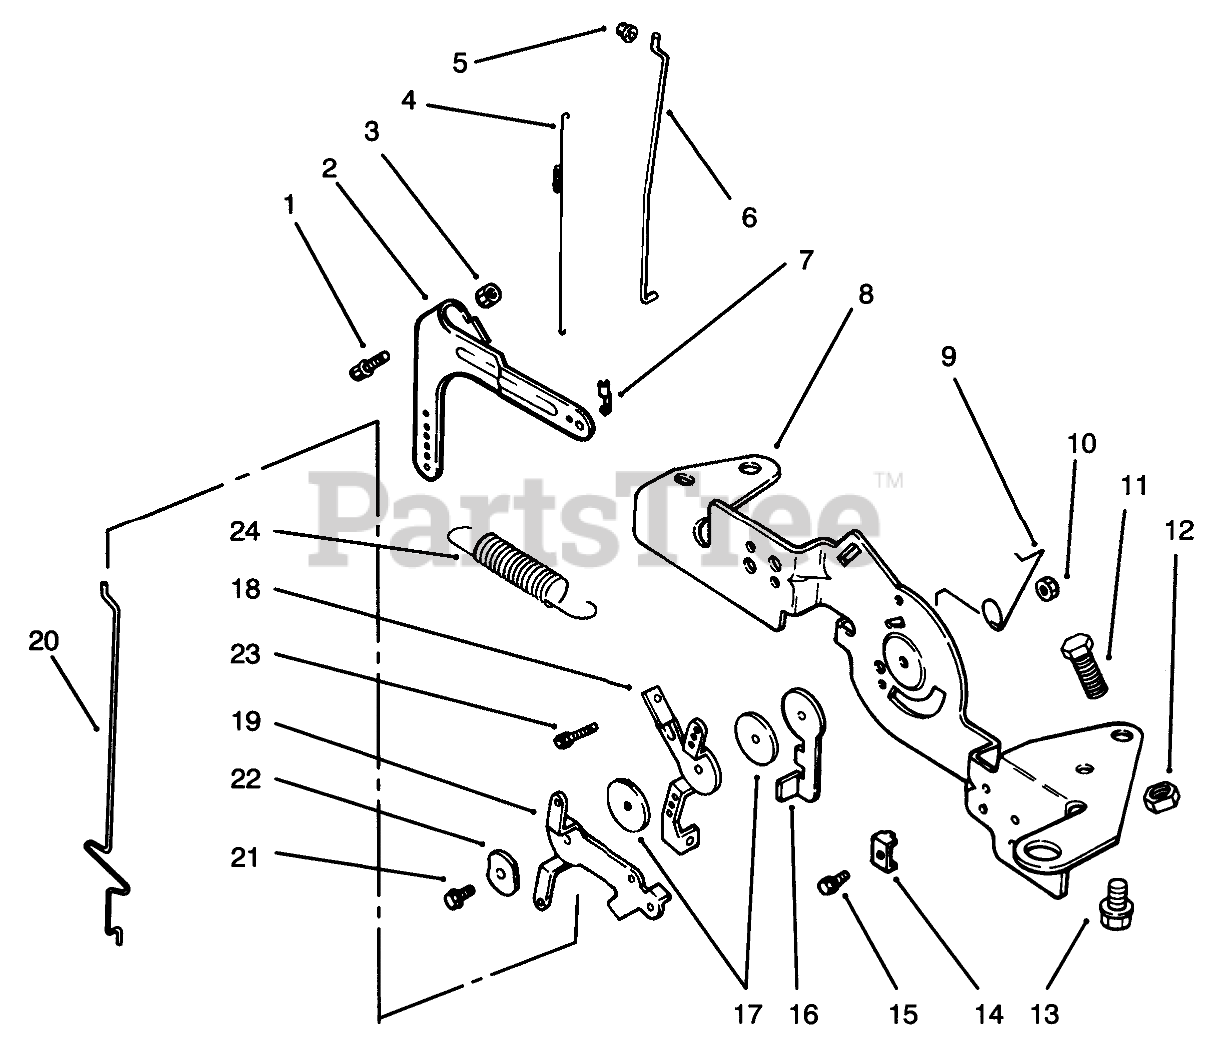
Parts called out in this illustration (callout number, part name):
1	Screw M6x1.0x25 (Only On: 72103)
2	Lever-Governor (Only On: 72103)
3	Nut M6x1.0 (Only On: 72103)
4	Spring-Linkage (Only On: 72103)
5	Bushing-Linkage (Only On: 72103)
6	Linkage-Throttle (Only On: 72103)
7	Bushing-Linkage (Only On: 72103)
8	Bracket-Control (Only On: 72103)
9	Spring-Choke Return (Only On: 72103)
10	Nut M5x0.8 (Only On: 72103)
11	Screw M5x0.8x16 (Only On: 72103)
12	Nut-Hex M4x0.7 (Only On: 72103)
13	Screw M6x1.0x16 (Only On: 72103)
14	Clamp-Cable (Only On: 72103)
15	Screw M5x0.8x16 (Only On: 72103)
16	Lever-Throttle Actuator (Only On: 72103)
17	Washer (Only On: 72103)
18	Lever-Throttle Control (Only On: 72103)
19	Lever-Choke (Only On: 72103)
20	Linkage-Choke (Only On: 72103)
21	Screw M5x0.8x20 (Only On: 72103)
22	Washer-Wave (Only On: 72103)
23	Screw M4x0.7x24 (Only On: 72103)
24	Spring-Governor (Only On: 72103)
